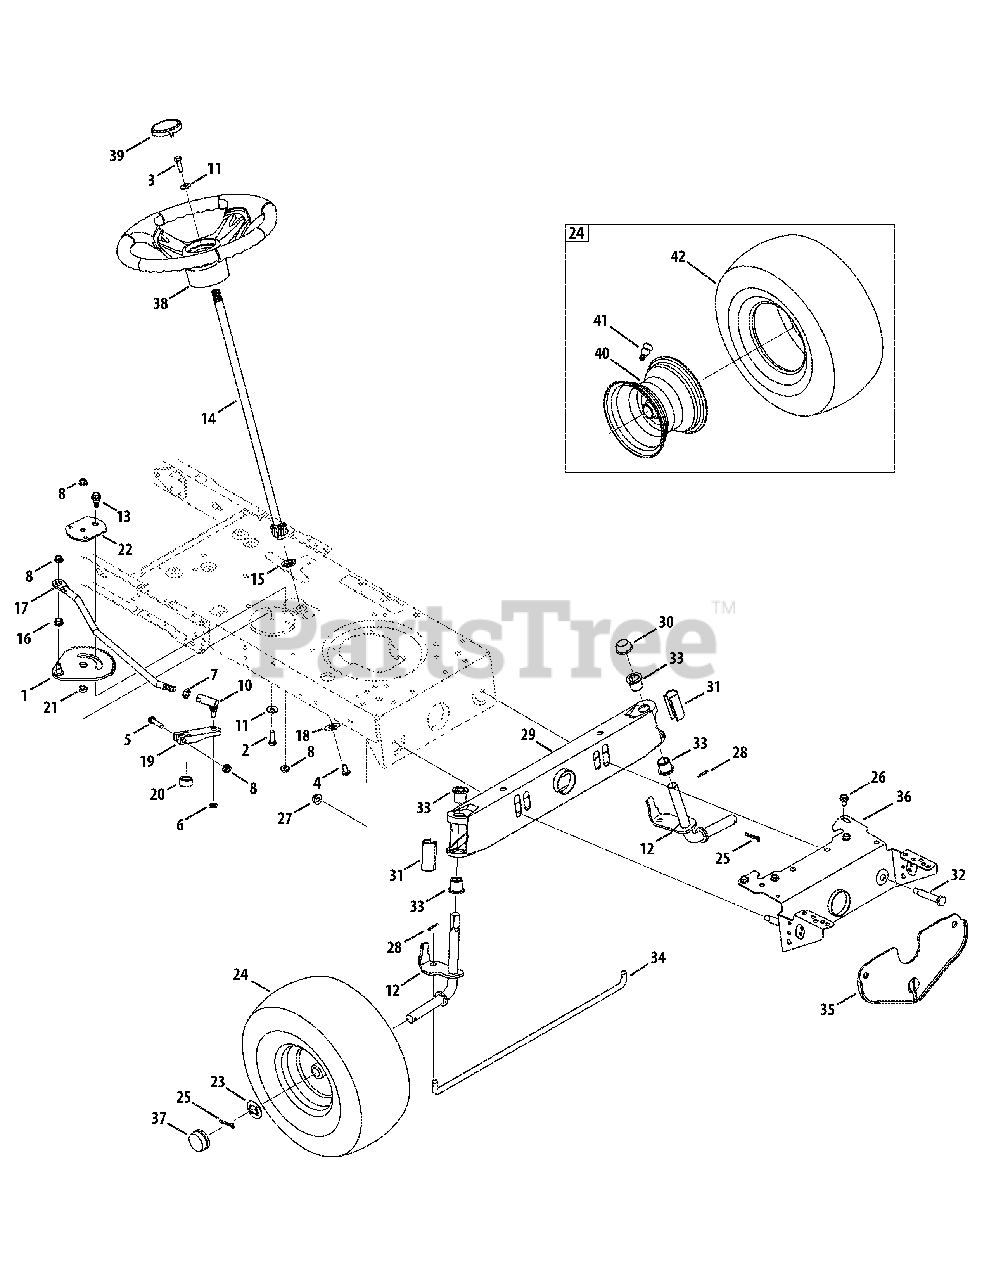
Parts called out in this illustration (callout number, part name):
1	Front Steering Gear Assembly
2	Hex Screw, 5/16-18 x 1.00
3	Hex Screw, 5/16-18 x 1.00, Lock
4	Machine Screw, 5/16-18 x .750
5	Hex Screw, 5/16-18 x 1.75
6	Jam Nut, 7/16-20
7	Jamlock Nut, 3/8-24
8	Flange Lock Nut, 5/16-18
9	Front RH Axle
10	Ball Joint, 7/16-20
11	Bell Washer, .340 x .872 x .060
12	Front LH Axle
12	Front RH Axle
13	Shoulder Bolt, 5/16-18 x .435 x .350
14	Steering Shaft, 5/8 x 22.08
15	Flange Bearing, 5/8
16	Plastic Bushing, .380 ID
17	Steering Link
18	Cap, 1.25 x .16
19	Steering Block
20	Spacer, .71 x .125 x .56
21	Spacer, .322 x .625 .21
22	Gear Segment Stabilizer Plater
23	Flat Washer, .781 x 1.590
24	Wheel Assembly
25	Cotter Pin, 5/32 x 1.25
26	Screw, 5/16-18 x .750
27	Flange Lock Nut, 3/8-16
28	Cotter Pin, .125 x .75
29	Pivot Axle
30	Push Nut, 3/4
31	Standard Axle Cap
32	Shoulder Bolt, 3/8-16 x .500 x 2.38
33	Flange Bearing, .760 x .941 x 1.0
34	Fixed Rod
35	Front Deck Hanger Bracket
36	Pivot Bar Bracket
37	Hub Cap
38	Steering Wheel
39	Sprig Cap
40	Rim Assembly, 6.0 x 4.0
41	Valve, tubeless Air
42	Tire, 13 X 5 X 6 Round Shoulder
